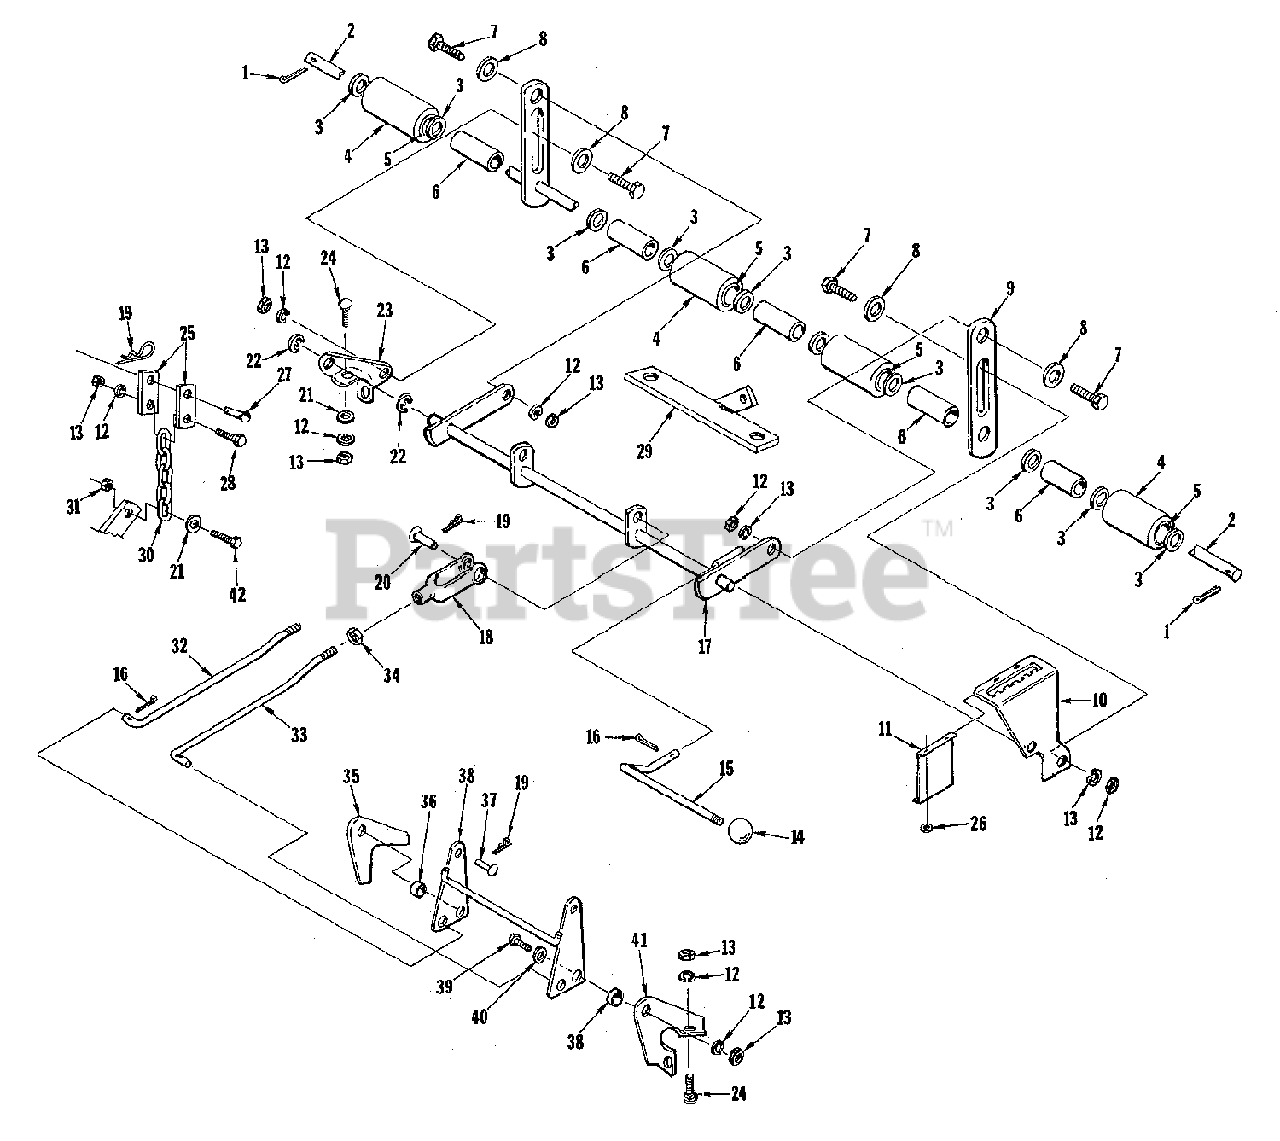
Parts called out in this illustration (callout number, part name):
1	PIN, Cotter, 3/16 x 1
2	SHAFT ASSEMBLY, Roller
3	WASHER, Flat
4	ROLLER ASSEMBLY
7	BOLT, Shoulder
8	WASHER, Flat, 7/16
10	QUADRANT, Mower Lift
11	SPRING, Control Lever
12	WASHER, Lock, 3/8
13	NUT, Hex, 3/8-16
15	LEVER, Control
16	PIN, Cotter, 1/8 x 1
17	ARM ASSEMBLY, Mower
18	YOKE, Rod End
20	PIN, Yoke, 1/2
21	WASHER, Flat, 3/8
22	RING, Retaining
23	BRACKET, Pivot
24	BOLT, Carriage, 3/8-16 x 3/4
25	LINK, Mower Lift
26	WASHER, Flat, 3/16
28	SCREW, Hex Cap, 3/8-16 x 1
31	NUT, Hex, 5/16-18
32	ROD, Adjusting (R.H.)
33	ROD, Adjusting (L.H.)
34	NUT, Hex, Jam, 1/2-20
35	BRACKET, Mower, Front (R.H.)
36	SPACER, Pivot
37	PIN, Round Head, 3/8 x 1-1/2
38	LINK ASSEMBLY, Mower
39	SCREW, Hex Cap, 3/8-16 x 1-1/2
40	WASHER, Flat
41	BRACKET, Mower, Front (L.H.)
42	SCREW, Hex, 5/16-18 x 1
